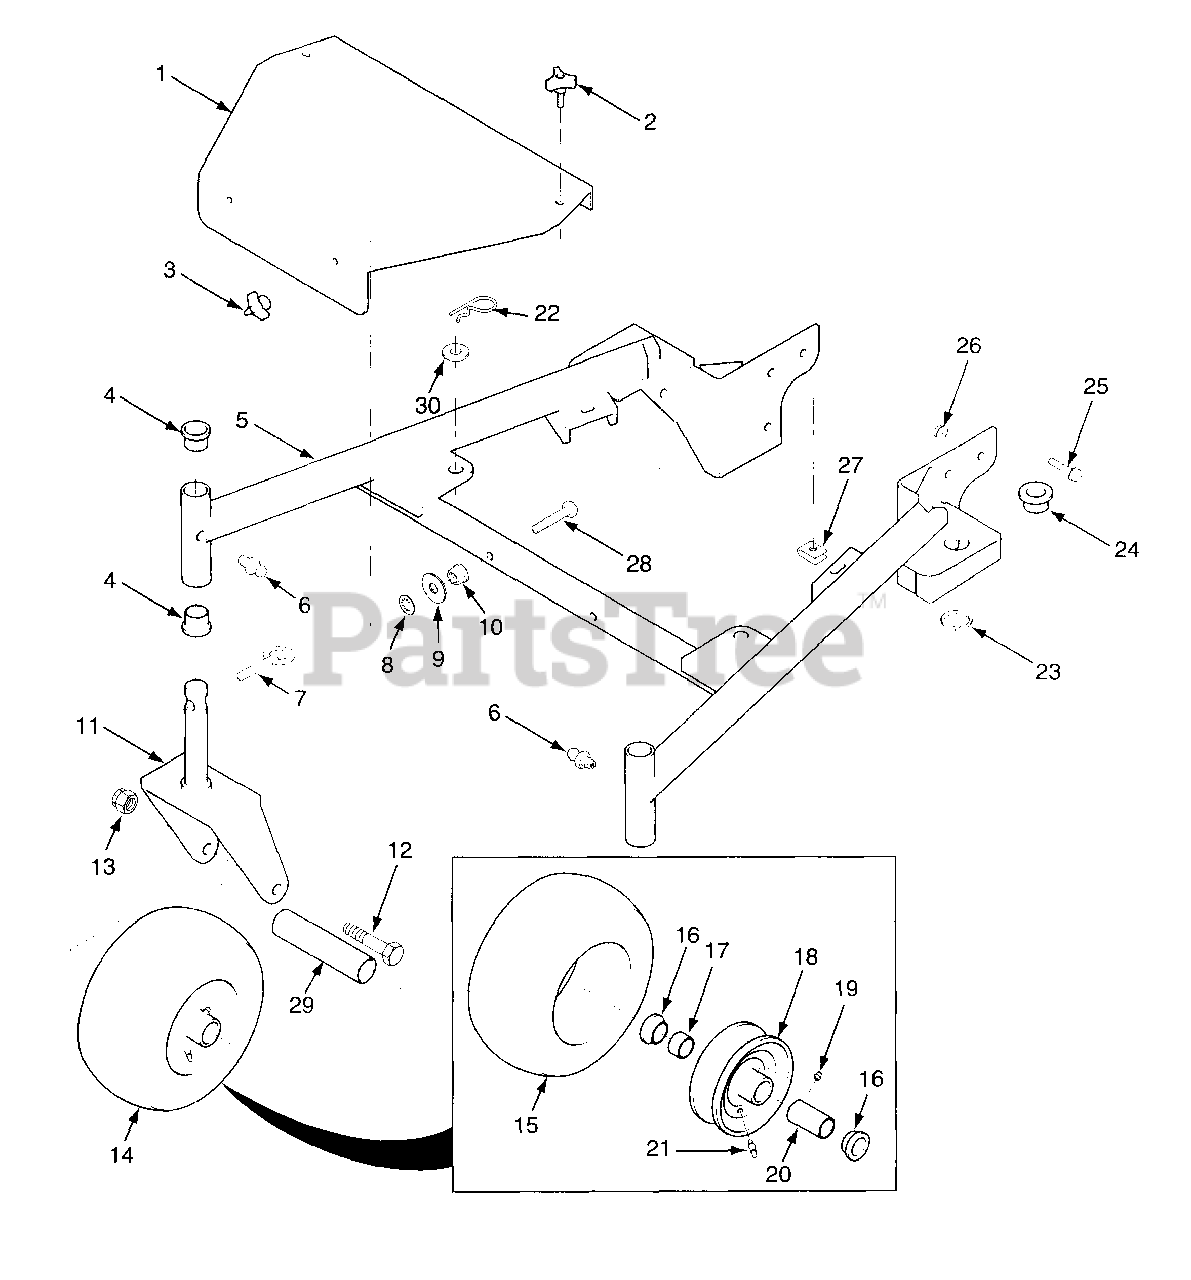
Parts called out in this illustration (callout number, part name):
1	Belt Cover With Decal
2	Knob With Stud
3	Knob, Deck Cover Mounting
4	Bushing, Caster
5	Frame Weldment, Deck Mounting - 48"
6	Grease Fitting Str. 1/4-28 Self Tap
7	Quick Pin, .438 Dia
8	Nut, Push-On - 3/8 Thd.
9	Flatwasher, 3/8 (.391 x .938 x .105)
10	Nut, 3/8-16 Serrated Flange Hex Head
11	Yoke, Caster Wheel
12	Capscrew, Hex Head 1/2-13 x 6.50"
13	Locknut, 1/2-13 Elastic Stop
14	Wheel Assembly, Caster
15	Tire, 11 x 4.00-5
16	Retainer
17	Roller Bearing
18	Rim, 5.0 x 2.75 With Zerk & Valve
19	Grease Fitting Str.1/4-28
20	Roller Bearing .625 x 3.25"
21	Tire Valve
22	Hair Pin Cotter, .177 x 3.25"
23	Retaining Ring 3.50 Ext.
24	Bushing, Deck Adjustment Pin
25	Capscrew, Hex Head 7/16-14 x 1.0"
26	Nut, 7/16-14 Serrated Flange Hex
27	U-Nut, 3/8-16
28	Capscrew, Hex Head 3/8-16 x 2.25"
29	Sleeve, Caster Wheel
30	Flatwasher, 5/8 - (.688 x 1.75 x .134)
